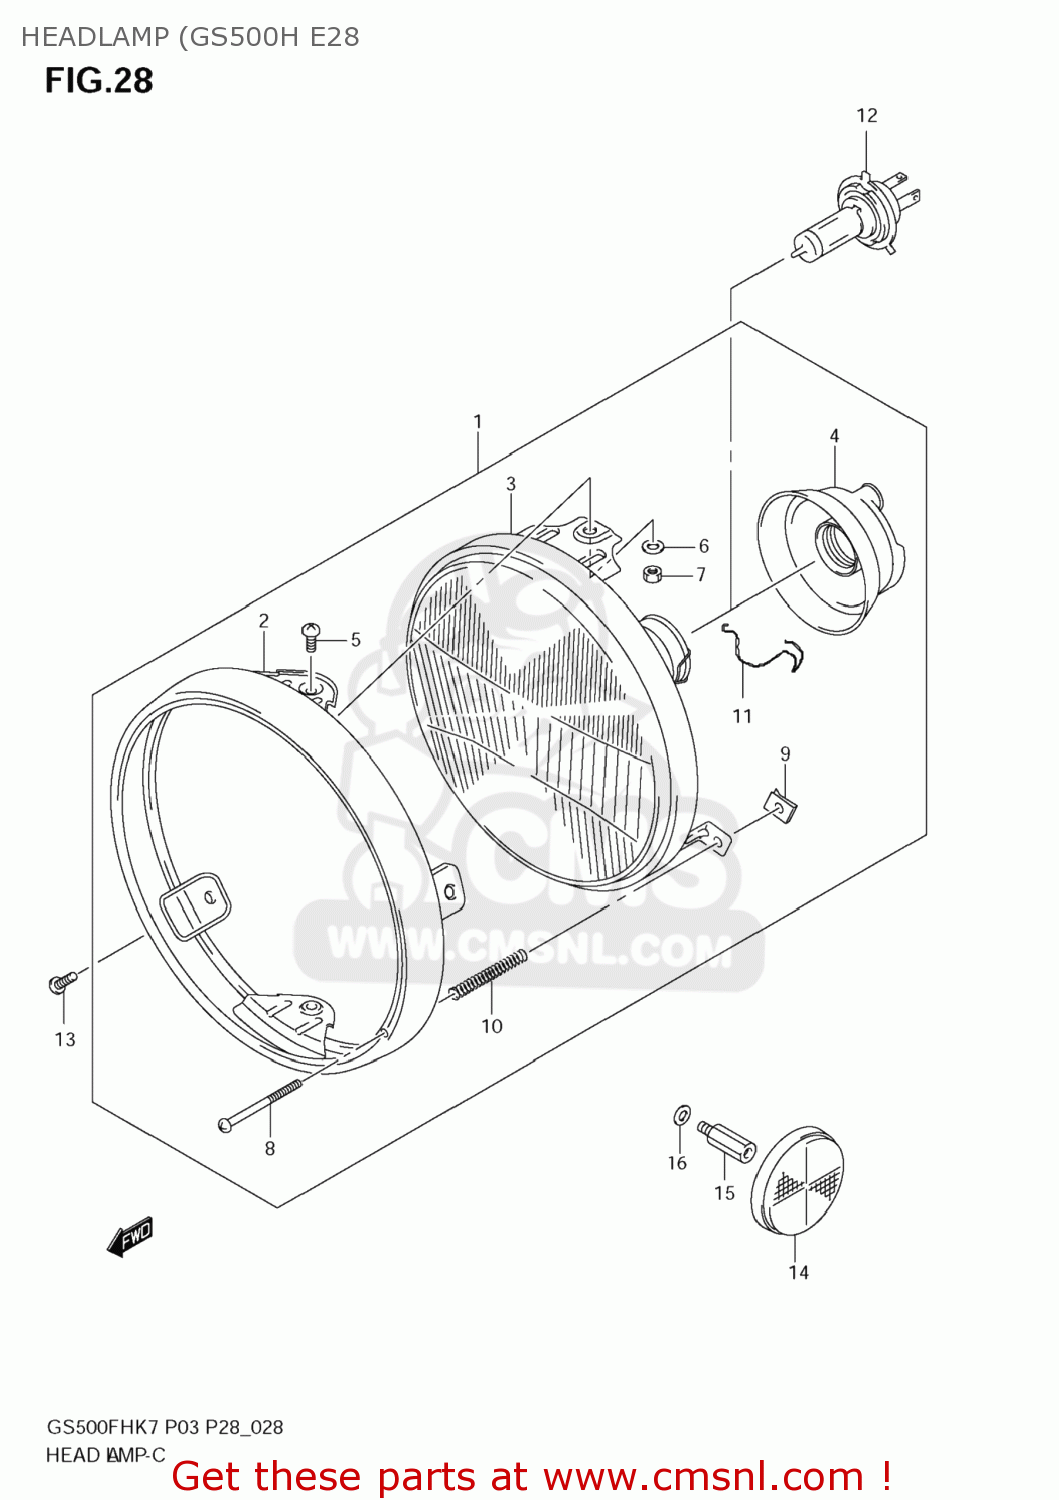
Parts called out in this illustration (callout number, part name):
1	HEADLAMP ASSY
2	RIM
3	LAMP UNIT
4	COVER, SOCKET
5	SCREW
6	LOCK WASHER
7	NUT
8	SCREW,ADJUSTIN
9	NUT
10	SPRING
11	SPRING
12	BULB(12V60/55W,H4)
13	SCREW 5X12
14	REFLECTOR,REFLEX
15	BOLT(5X10)
16	WASHER
